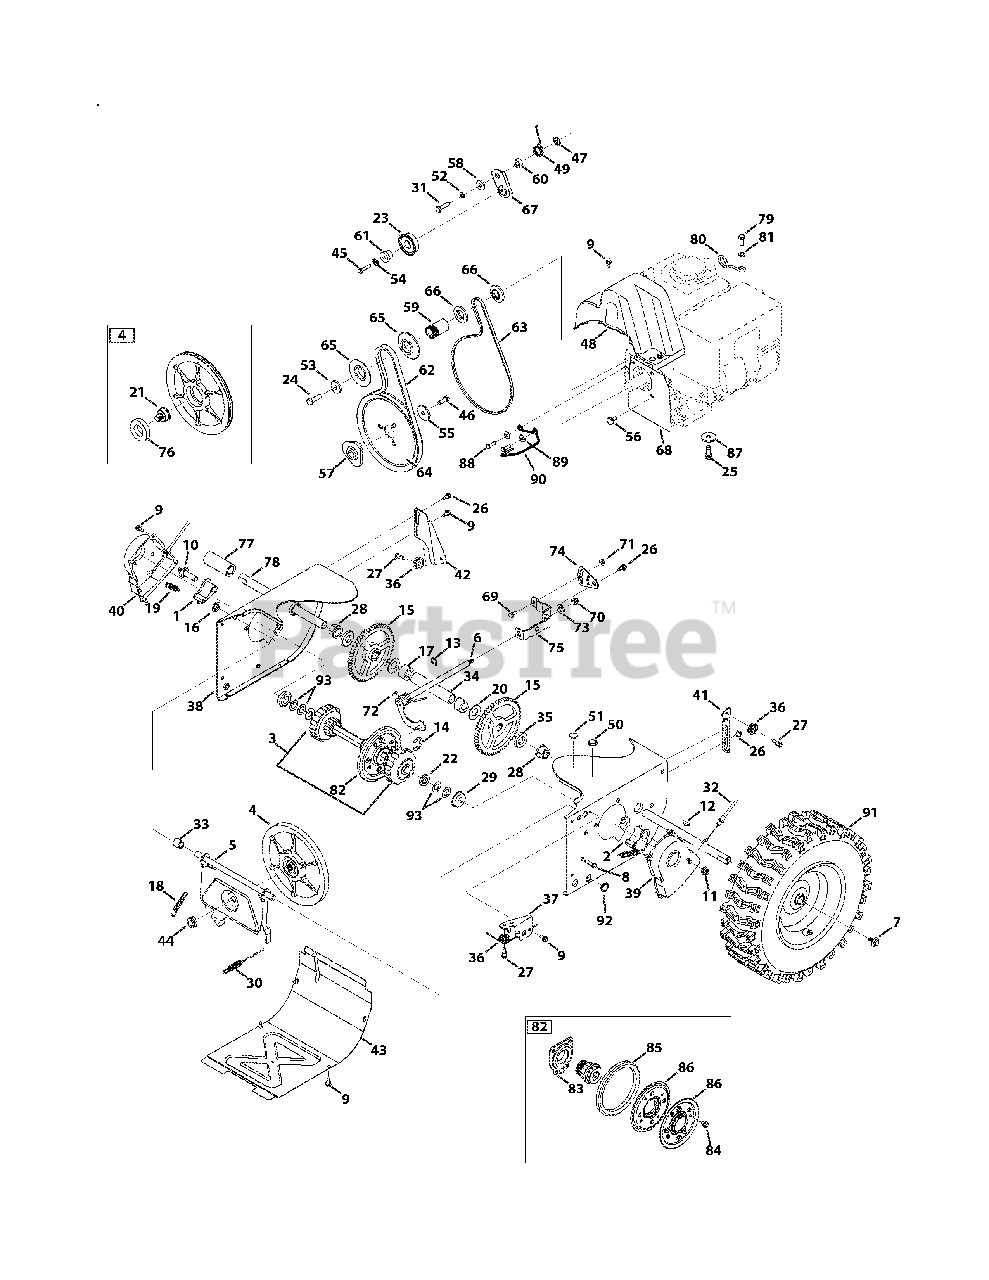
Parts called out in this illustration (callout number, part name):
1	Dogg Assembly, RH
2	Dogg Assembly, LH
3	Drive Shaft Assembly
4	Friction Wheel Disc Assembly
5	Friction Wheel Support
6	Rod Shift Assembly
7	Screw, 5/16-24 x .750
8	Screw, 1/4-20 x 1.000
9	Screw, 1/4-20 x .625
10	Actuator Shaft
11	Nut, Flangelock, 3/8-16
12	Hi-Pro Key, 3/16 x 3/4 DIA
13	E-Ring
14	Retainer Ring
15	Gear, 56T
16	Nut, Speed, .500
17	Spacer, .76 x .75
18	Extension Spring, .380 x 2.500
19	Extension Spring, .500 x 1.71
20	Washer, Flat, .76 x 1.49
21	Friction Pin, Disc Bearing
22	Spacer, .68 ID x 1.25 OD x .20
23	Pulley Assembly
24	Hex Head Screw, 3/8-24 x 1.25
25	Taptite Sems Screw, 3/8-16 x 1.000
26	Screw, Shoulder, .368 x .113 x 1/4-20
27	C Screw, Shoulder, .340 x .335 x 1/4-28
28	Hex Flange Bearing, .75 ID
29	Ball Bearing, 17 x 40 x 12
30	Drive Clutch Cable
31	Hex Head Screw, 5/16-24 x 1.25
32	Steering Cable
33	Spacer, .508 x .75
34	Axle Support Tube
35	Spacer, Axle
36	Roller Cable
37	Auger Cable Guide Bracket
38	Wheel Drive Frame (24"/28")
39	Shaft Retainer, LH
40	Shaft Retainer, RH
41	Auger Clutch Cable Guide Bracket
42	Drive Clutch Cable Guide Bracket
43	Frame Cover
44	Nut, Flange, 5/8-18
45	Taptite Screw, 1/4-20 x 1.250
46	Hex Head Screw, 5/16-24 x .875
47	Nut, Push-On, .25 DIA
48	Belt Cover, 4-Way lrg. block
49	Spring, Torsion, .850 x .333
50	Plug, 3/8 ID
51	Plug, 1/2 ID
52	Washer, Lock, 5/16
53	Washer, Flat, .45 x 1.5
54	Washer, Lock, 1/4
55	Washer, Flat, .34 x 1.50
56	Screw, Shoulder
57	Pulley Adapter, .75 DIA
58	Spacer, Shoulder, .3175 x .500
59	Spacer, .875 x 1.185
60	Spacer, .340 x .750
61	Spacer, Shoulder, .260 x .785
62	Auger Drive Belt, 4-Way lrg. block
63	Wheel Drive Belt, 4-Way lrg. block
64	Auger Pulley, 8.1 x .5
65	Pulley, Half, 4L-V x 2.600
66	Pulley, Half, 3/8-V x 1.7160
67	Drive Idler Bracket
68	Cover Plate, 4-Way lrg. block
69	Hex Head Screw, 1/4-20 x .620
70	Nut, Flangelock, 5/16-18
71	Nut, Flangelock, 1/4-20
72	Spring, Torsion, .750 x .968
73	Washer, Flat, .469 x .875 x .105
74	Speed Selector Pivot Bracket
75	Speed Selector Shift Bracket
76	Ball Bearing, 30 x 55 x 13
77	Spacer, 1.25 x .75 x 3.00
78	Axle, .75 x 11.12
79	Hex Head Screw, 1.25 x 20
80	Cable Guide
81	Washer, Flat, .330 x .630
82	Friction Wheel Assembly
83	Bearing Assembly, Friction Wheel
84	Screw, 5/16-18 x .750
85	Friction Wheel, 5.5 OD
86	Friction Wheel Plate
87	Washer, Flat, .38 x 1.38
88	Hex Head Screw, 5/16-24 x 1.00
89	Washer, Flat, .349 x .879
90	Belt Guide
91	Wheel, LH, 16 x 6.5-8
91	Wheel, RH, 16 x 6.5-8
92	Plug, 5/8 Hole
93	Flat Washer, .67 x 1.174 x .02
